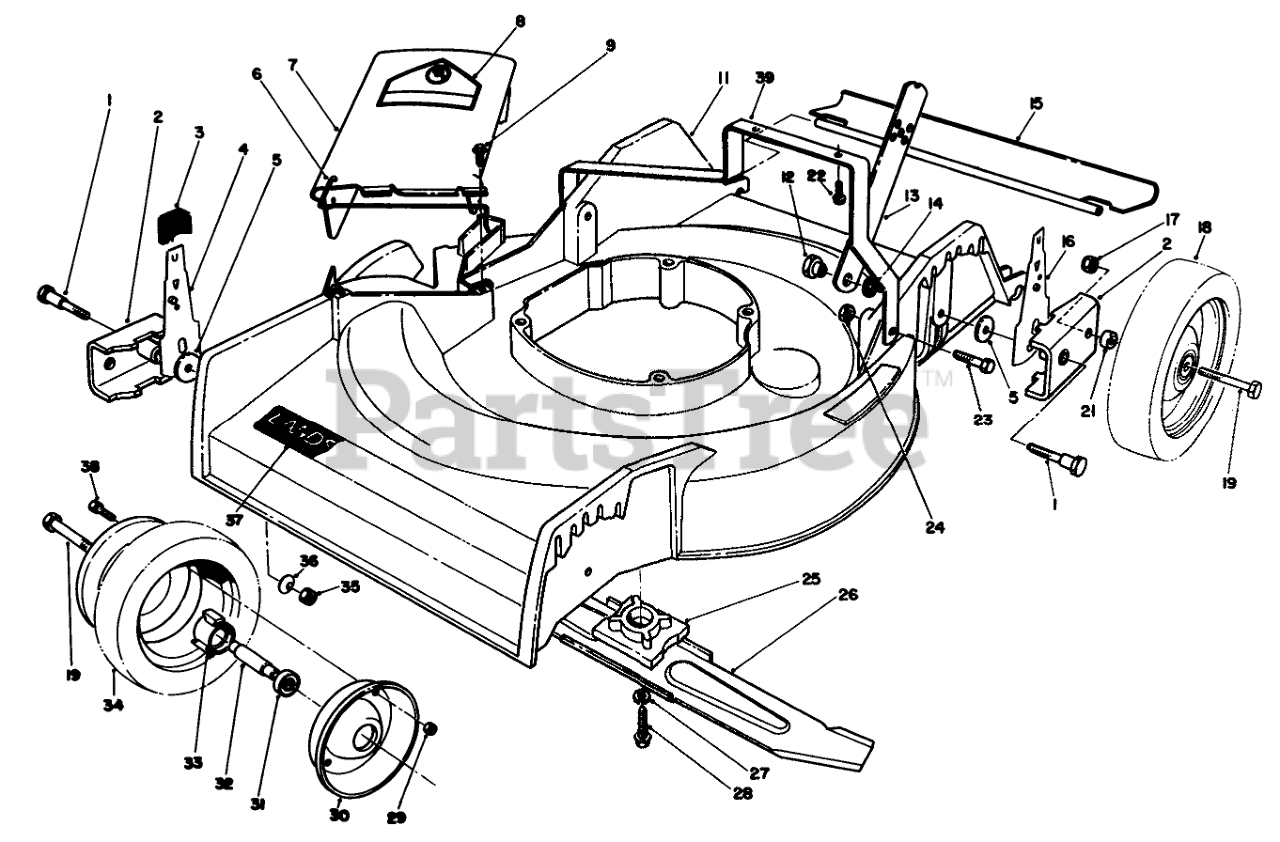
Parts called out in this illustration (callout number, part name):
1	PIVOT SCREW
2	HP PIVOT ARM ASM
3	KNOB-ARM
4	SPRING ARM ASSEMBLY
5	PIVOT WASHER
6	SPRING HINGE
7	Deflector Assembly (Incl. Ref. #6 & 8)
8	DECAL-DANGER
9	SCREW-HWH
11	HOUSING W/ DECAL
12	HANDLE PIVOT NUT
13	21 HANDLE LATCH
14	SPACER
15	SHIELD - TRAILING
16	SPRING ARM ASSEMBLY
17	NUT-LOCK, NI
18	WHEEL AND TIRE ASM
19	SCREW-HH
21	SPACER-WHEEL
22	SCREW-HWH
23	SCREW-HH
24	NUT-HEX
25	BLADE RETAINER
26	Blade
27	WASHER-LOCK
28	SCREW-HH
29	NUT-LOCK, NI
30	Wheel-Half
31	BEARING-WHEEL
32	SPACER-BEARING
33	HUB-BEARING
35	NUT-LOCK, NI
36	WASHER-BELLEVILLE
37	DECAL - LANDSCAPER
38	SCREW-HH
39	BASE TANK
